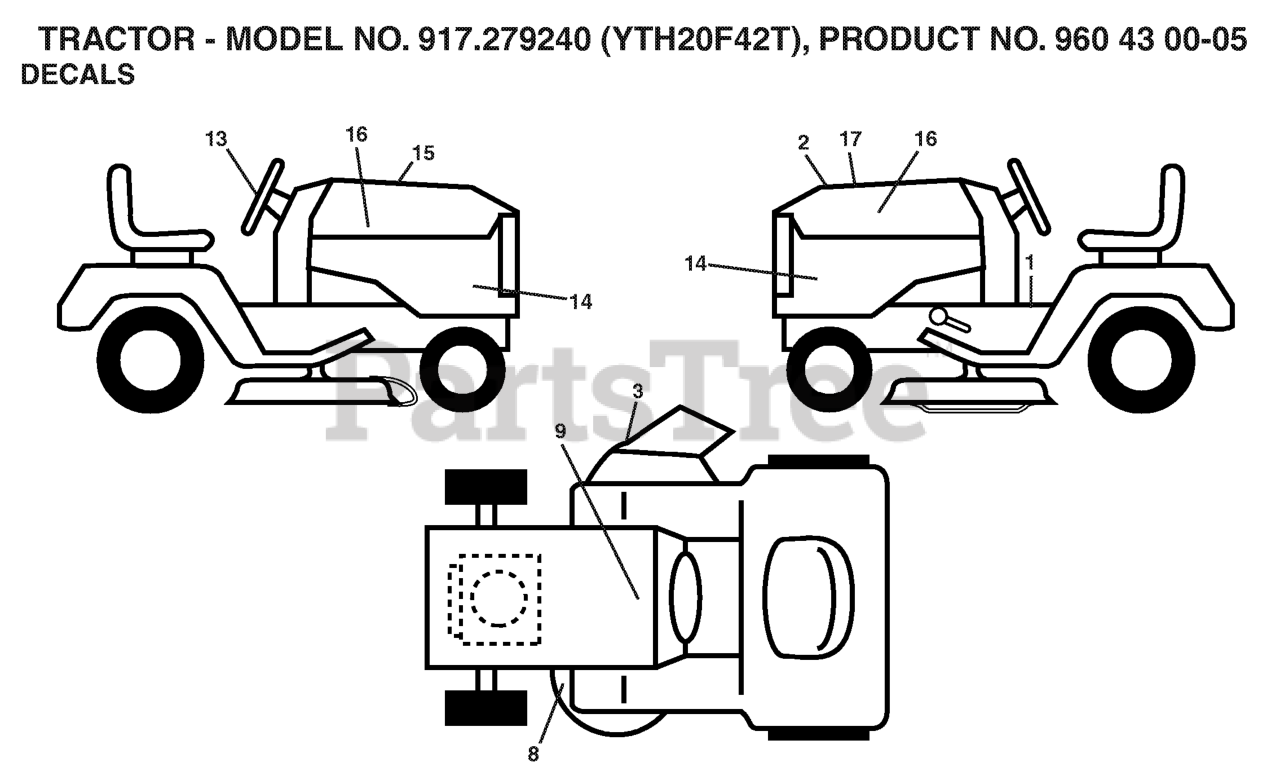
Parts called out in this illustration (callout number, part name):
1	DECAL.FENDER.OPER.TEX.
2	DECAL.HOOD.TOP.INSERT.
3	DECAL.WARN.KEEP.HAND.AWAY
8	DECAL V BELT SCHEMATIC
9	DECAL BTRY SYMBOLS
13	DECAL.STEERING.HUSQ.BLUE
14	DECAL.PANEL.SIDE.YTH20F42T
15	DECAL HOOD CUST. RESP.
16	DECAL.HOOD.NAMELOGO.HUSQ
17	DECAL.PLMNT.KOHL.20HP.
